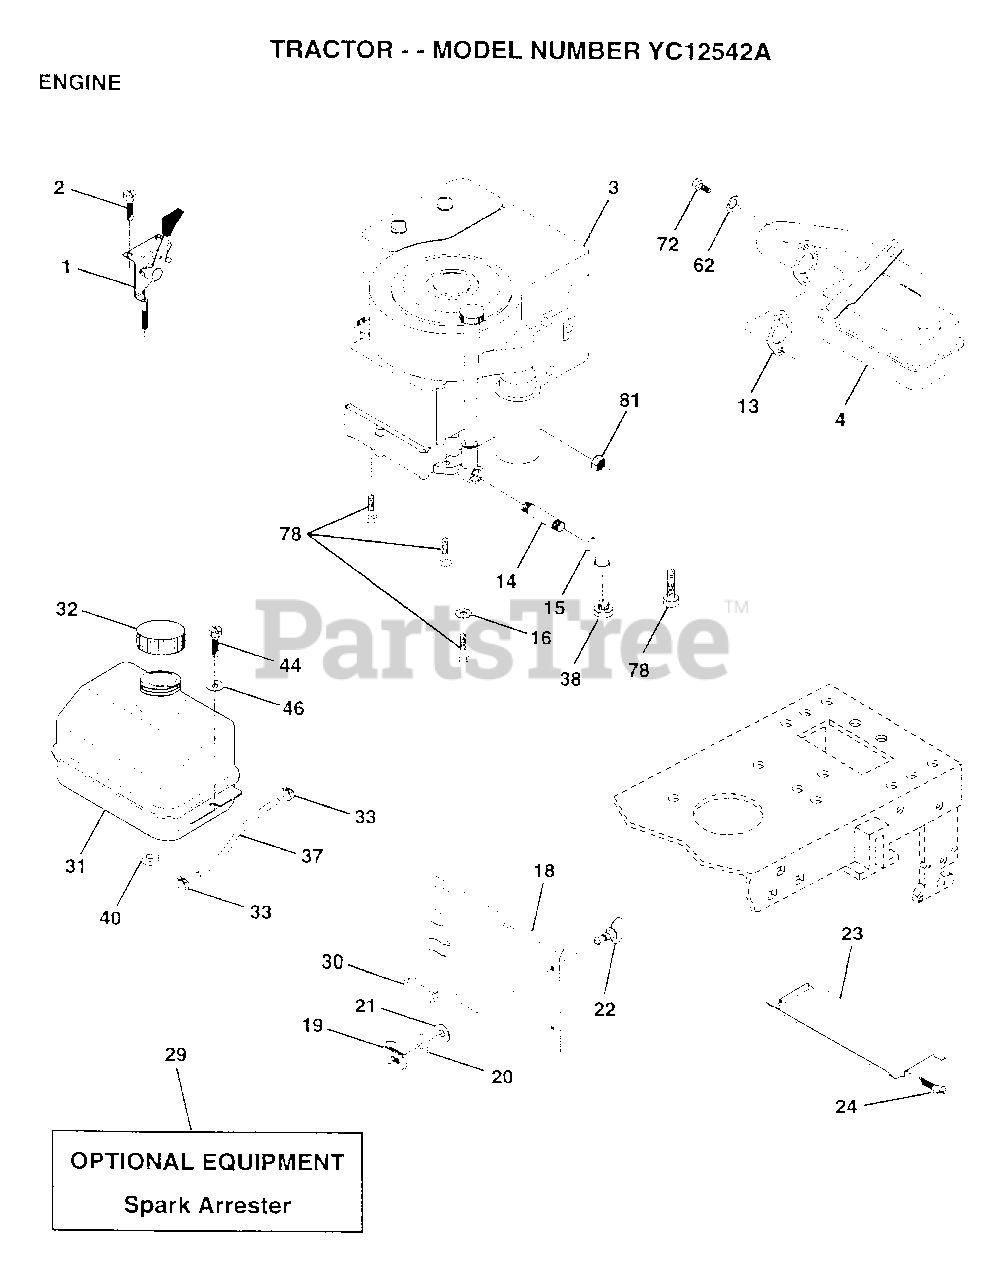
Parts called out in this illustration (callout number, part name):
1	THROTTLE CONTROL
2	SCREW LT
4	MUFFLER
14	PIPE NIPPLE
15	ELBOW
16	LOCKWASHER
18	SHIELD HEAT
19	RECEPTACLE LT
20	RETAINER LT
21	WASHER
22	STUD.1/4.TURN
23	HEAT SHIELD
24	SCREW
31	TANK.FUEL.LT.
32	CAP ASM FUEL
33	HOSE CLAMP
37	LINE FUEL
44	SCREW HEX CRT
46	WASHER
62	LOCKWASHER
72	SCREW
78	SCREW
81	NUT
